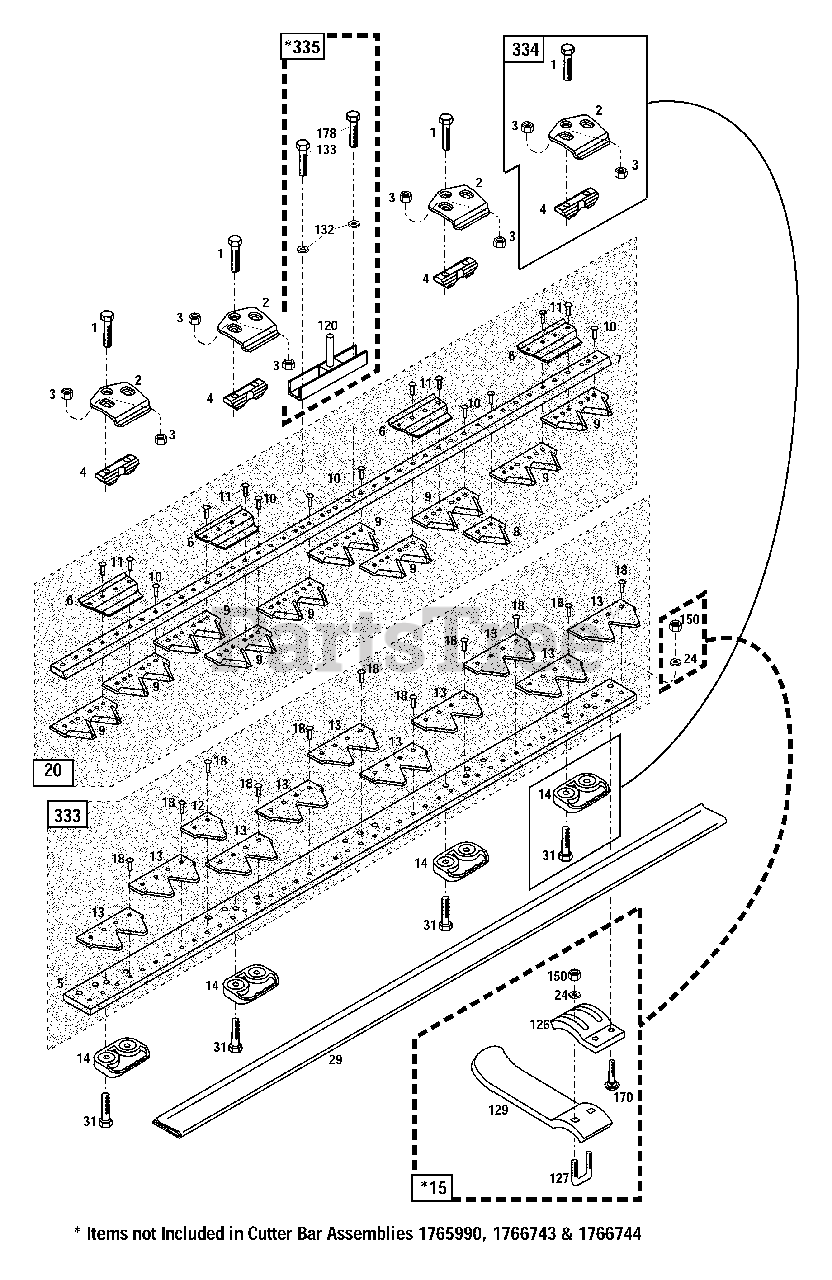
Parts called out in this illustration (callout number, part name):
1	Hex Hd. Screw, M8 x 0.30
2	Hold-Down Clip
3	Lock Nut, M8
4	Knife Guide
5	34" Ledger Plate Bar
6	Wear Plate
7	34" Blade Knife Bar
8	Blade (single)
9	Blade (double) 34"
10	Rivet Section, 5 x 17 (pack of 12)
11	Rivet Section, 5 x 20 (pack of 12)
12	Ledger Plate (single)
13	Ledger Plate (double)
15	Skid Assembly
18	Ledger Rivet, 6 x 20 (pack of 12)
20	34" Blade Assembly
24	Flat Washer, 5/16
29	Blade Guard, 34"
31	Hex Hd. Screw, M8 x 45
120	Knife Head
126	Shoe Holder
127	U-Bolt, 5/16
132	Flat Washer (hardened), 5/16
133	Hex Hd. Capscrew, M8 x 12
150	Nylock Nut, 5/16-18
170	Carriage Bolt, 5/16-18 x 1, Grade 5
178	Loctite(R) Thread Compound
333	34" Ledger Plate Assembly
334	Hold-Down Clip Kit
335	Knife Head & Pitman Kit
